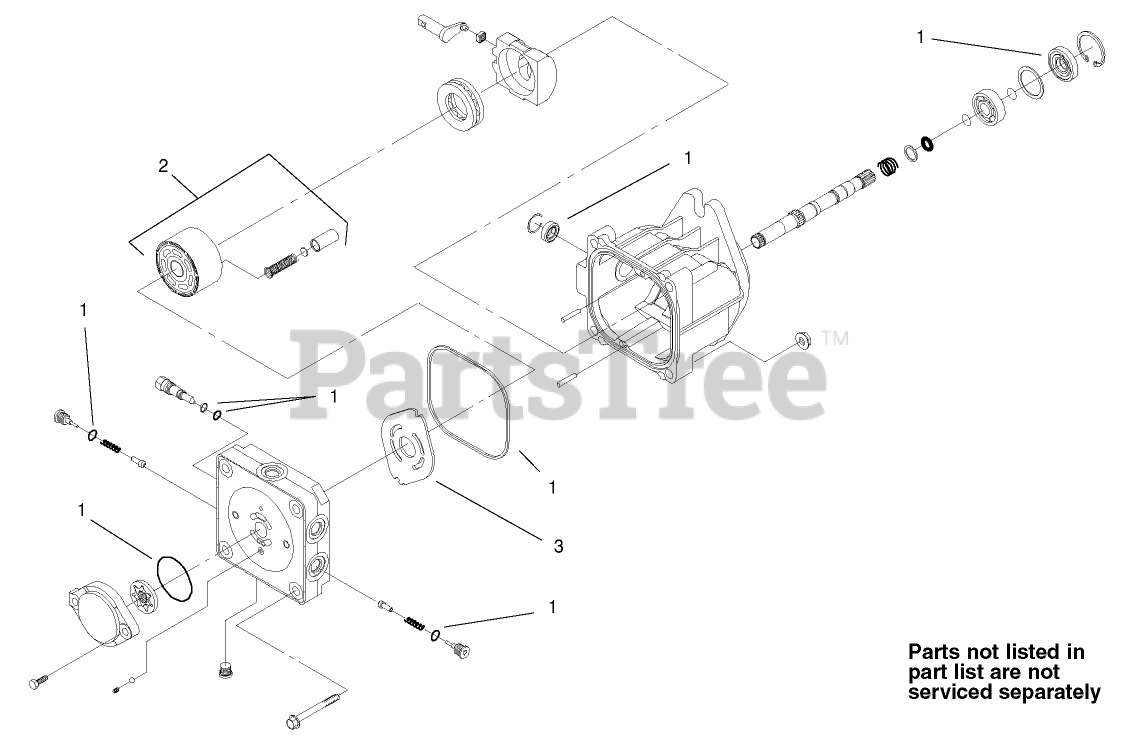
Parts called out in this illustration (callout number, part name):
1	OVERHAUL SEAL KIT
2	KIT-BLOCK, CYLINDER
3	PLATE-VALVE
